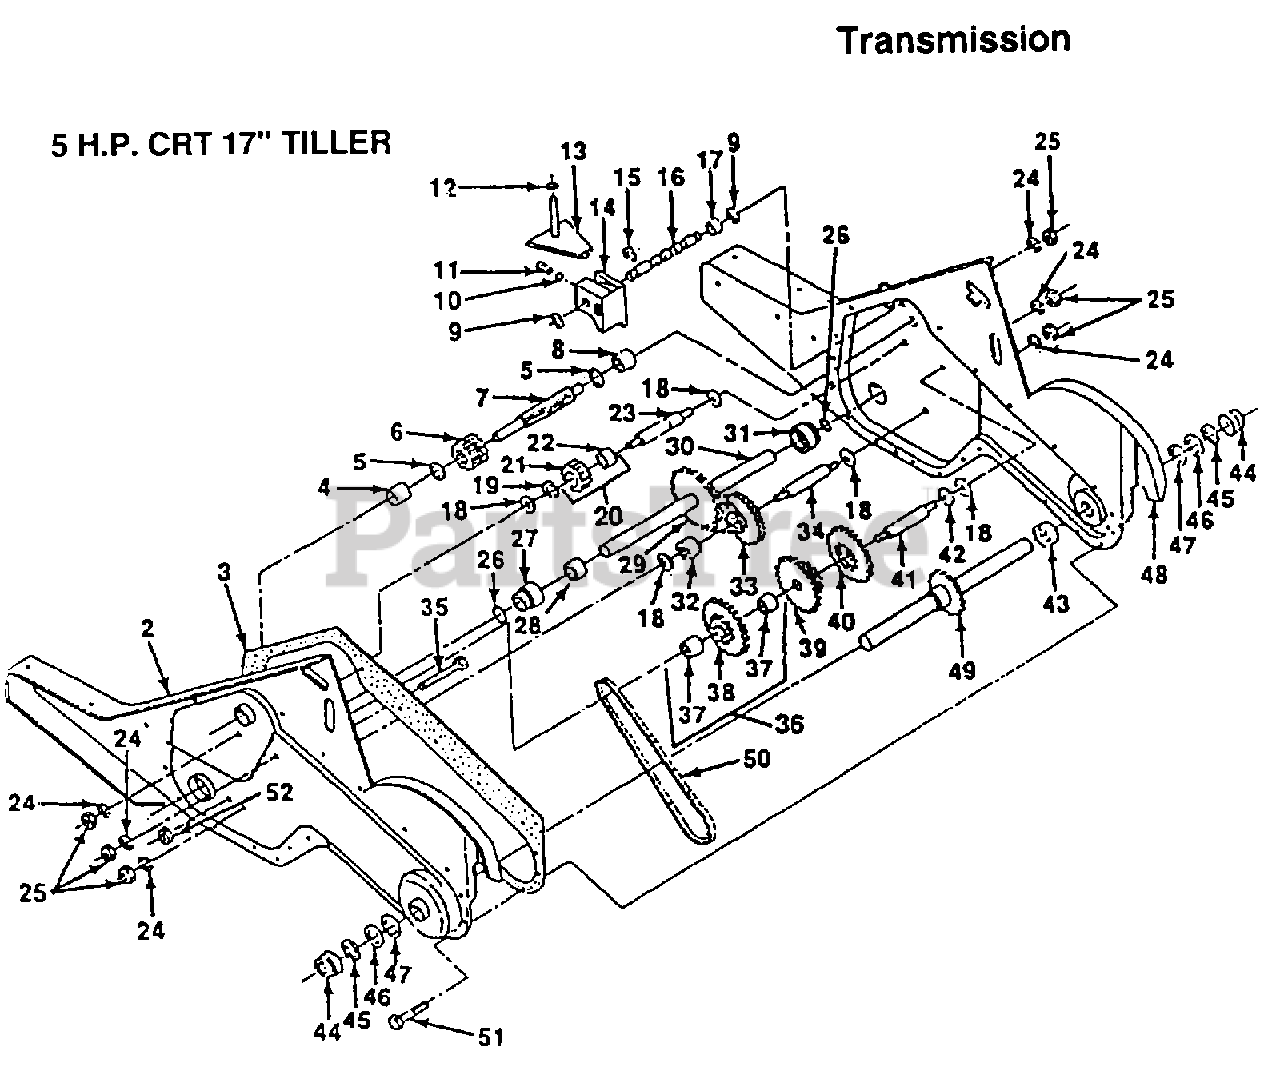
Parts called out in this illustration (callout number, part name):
3	GASKET TI
4	NEEDLE BRNG LT
5	"T, BEARING"
6	PINION-INPUT CRT
7	SHAFT-INPUT CRT
8	"TI, BEARING"
9	WASHER SEAL CRT
11	SPRING-SHIFT CRT
12	O-RING TI
13	ARM ASSY CRT
14	SHIFT FORK TI
15	KLIP RING
16	SHAFT SHIFT CRT
17	SPACER SPLIT CRT
18	WASHER
19	KLIP RING
20	GEAR ASSY CRT
21	GEAR-REV IDLR CRT
22	NEEDLE BEARING TI
23	SHAFT CRT
24	LOCKWASHER
25	NUT.ASF.HEX.7/16
26	O RING CRT
27	"CRT, BEARING"
28	BUSHING TI
29	CHAIN CRT
32	SPACER TI
33	SPRCKT 8 GEAR CRT
34	SHFT 2ND RED. CRT
35	SCRW WHIZ LOK CRT
37	BEARING
39	GEAR TI
40	GEAR TI
41	REDUCTION SHFT TI
42	BRNG RACE
43	SPACER TI
44	CUP.FORMED.
45	RING SPIRAL CRT
49	SHAFT ASSY TI
50	CHAIN.50 LINK TI
51	SCREW CRT
52	NUT.HEX.5/16-18
53	GREASE PREMIUM-1
